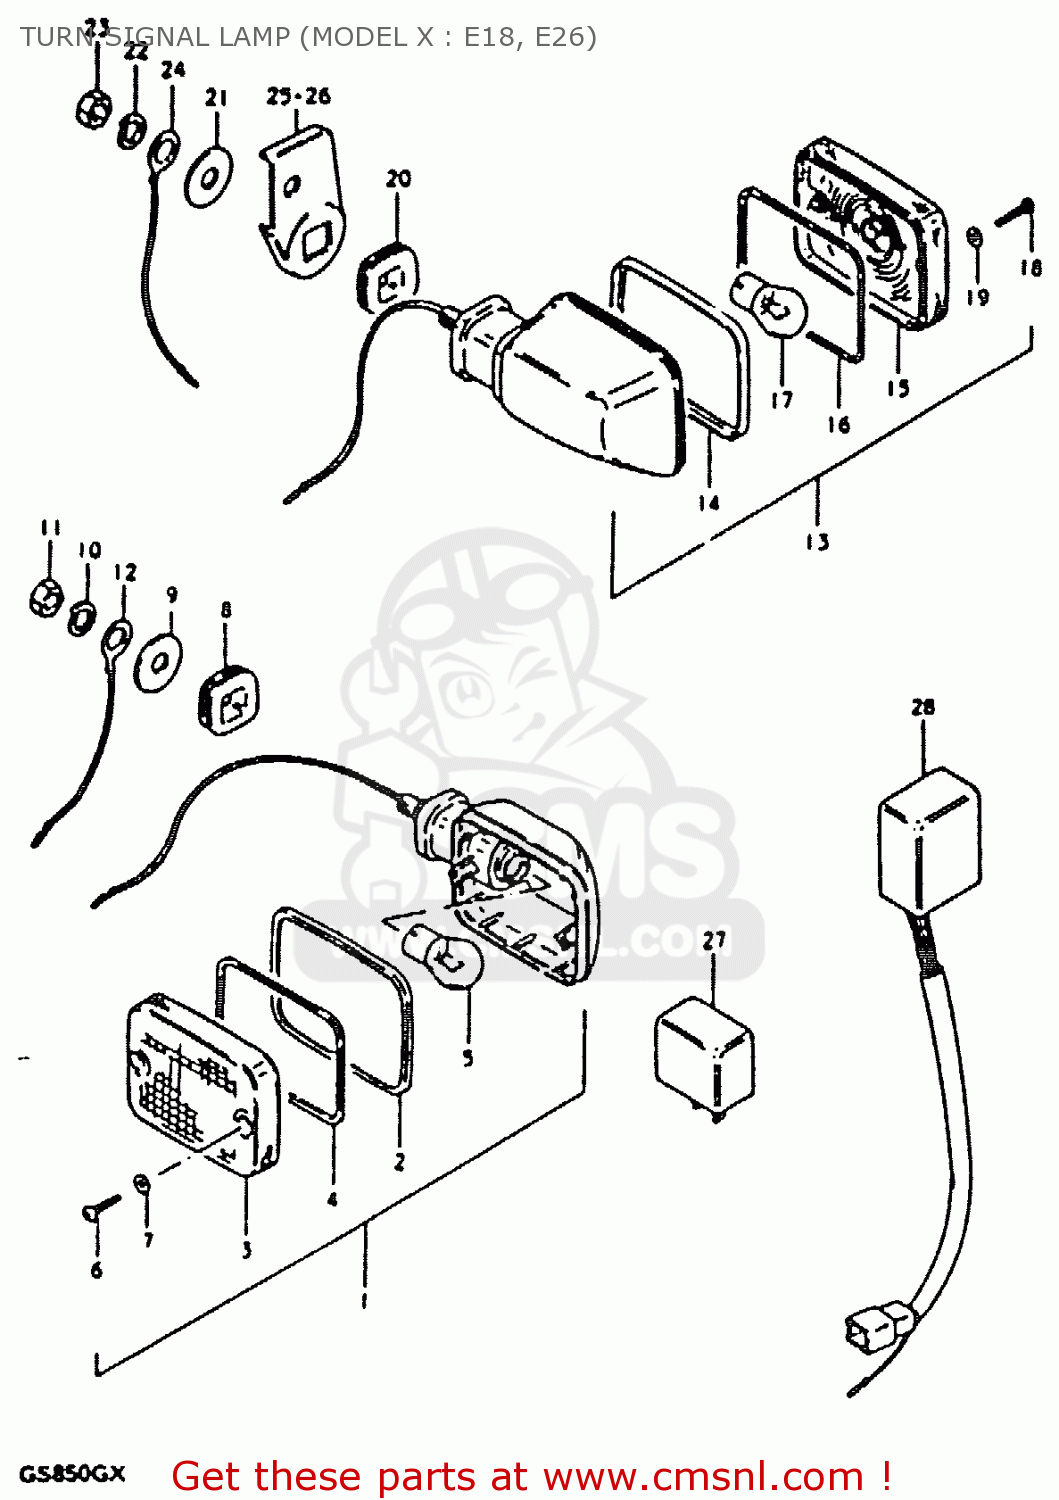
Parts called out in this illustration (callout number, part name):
1	LAMP, FRONT TURN SIGNAL
2	RIM
3	LENS
4	GASKET (NAS)
5	BULB 12V 21W
6	SCREW
7	GASKET (NAS)
8	CUSHION
9	WASHER (10.5X30X2.3)
10	LOCK WASHER
11	NUT
12	LEAD WIRE,EARTH
13	LAMP, REAR TURN SIGNAL
14	RIM
15	LENS
16	GASKET (NAS)
17	BULB 12V 21W
18	SCREW
19	GASKET (NAS)
20	CUSHION
21	WASHER (10.5X30X2.3)
22	LOCK WASHER
23	NUT
24	LEAD WIRE,EARTH
25	BRACKET,RR TURNSIGNAL LAMP,R
26	BRACKET,RR TURNSIGNAL LAMP,L
27	RELAY ASSY,TURNSIGNAL
28	UNIT,TURN SIGNAL CONTROL
